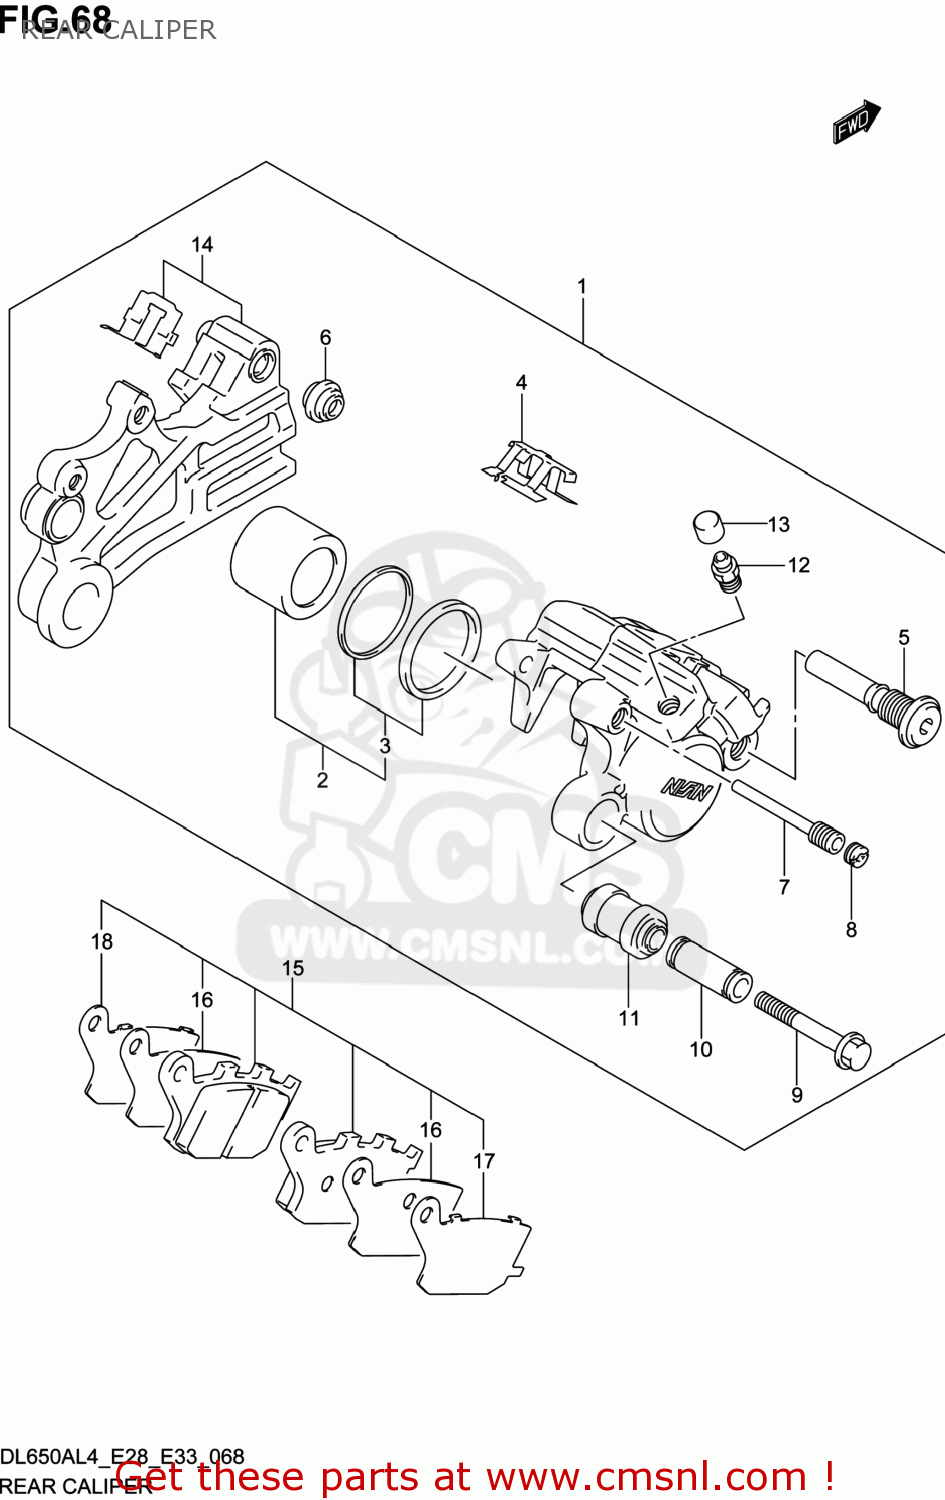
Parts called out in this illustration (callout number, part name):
1	CALIPER ASSY,RR
2	PISTON SET
3	SEAL SET,PISTON
4	SPRING,PAD
5	PIN,BOLT
6	BOOT
7	PIN,PAD
8	PLUG,PIN
9	BOLT
10	SLEEVE
11	BOOT,SLEEVE
12	BLEEDER
13	CAP,BLEEDER
14	BRACKET
15	PAD & RETAINER SET
16	INSULATOR
17	RETAINER
18	RETAINER
